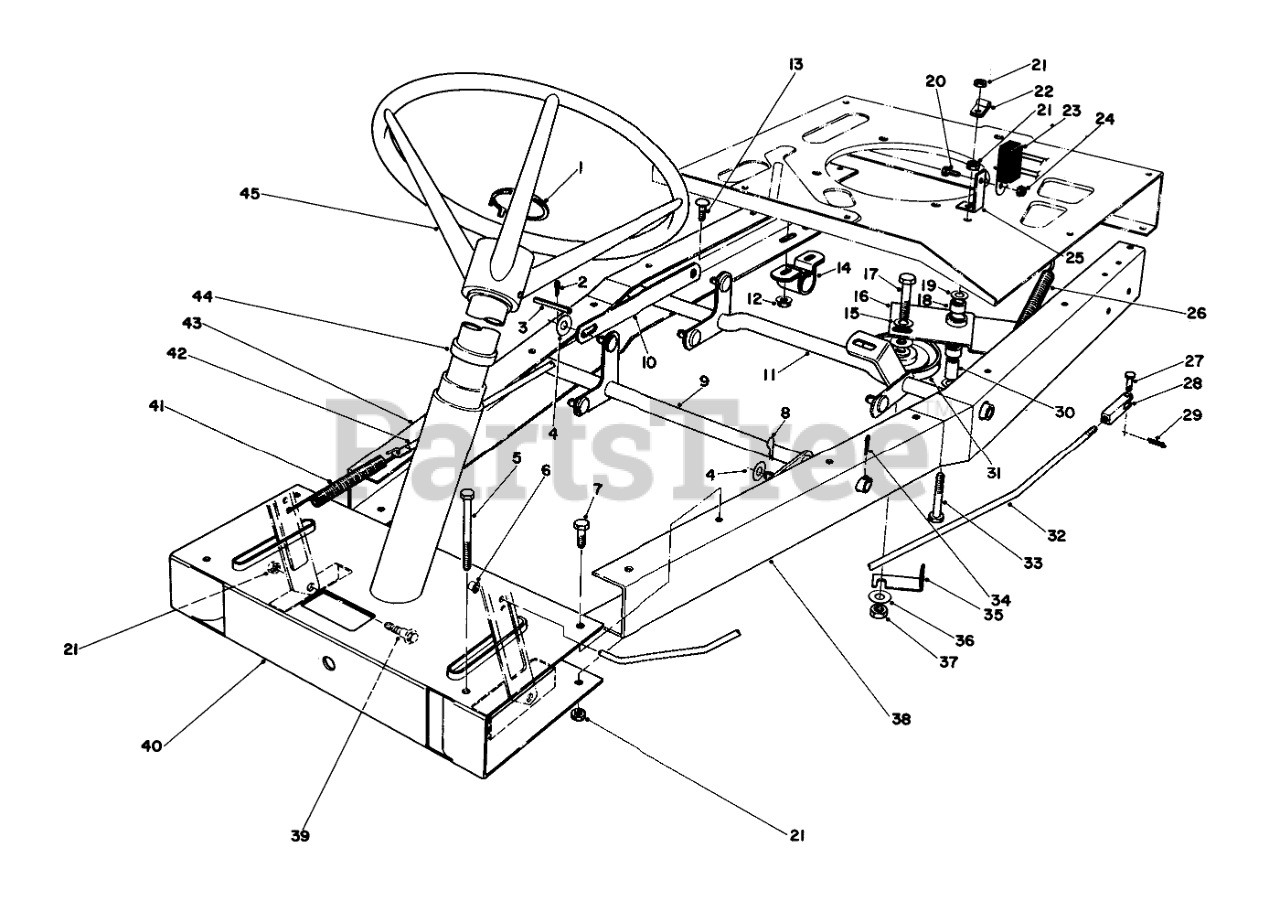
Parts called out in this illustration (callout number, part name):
1	Insert-Steering Wheel
2	PIN-COTTER
3	PIN-ROLL
4	WASHER-FLAT
5	SCREW-HH
6	PUSH ON SPEED NUT 1/4
7	SCREW-HH
8	PIN-COTTER
9	FRONT LIFT WA B
10	Linkage-Height Adj.
11	REAR HT ADJ WA B
12	NUT-HHF, WHIZ
13	SCREW-CARR
14	PILLOW BLOCK
15	WASHER-FLAT
16	Traction Idler Assembly (Incl . Ref. #18)
17	SCREW-HH
18	Bushing
19	WASHER-PLAIN
20	SCREW-HH
21	NUT-LOCK, CONE
22	CLIP-FUEL LINE
23	Control Module
24	NUT-KEPS
25	Mount-Module
26	Clutch Tension Spring
27	PIN-CLEVIS
29	PIN-COTTER
30	PIVOT SPACER
31	PULLEY-IDLER
32	Clutch Rod
33	SCREW-HH
34	PIN-COTTER
35	RETAINER-BELT
36	WASHER-FLAT
37	NUT-LOCK, SIDE
38	LH FRAME CHANNEL B
39	SCREW-SHOULDER
40	Front Frame
41	BRAKE TENSION SPRG O
42	Brake Rod
43	Frame-Channel R.H.
44	Steering Tube
45	Steering Wheel
